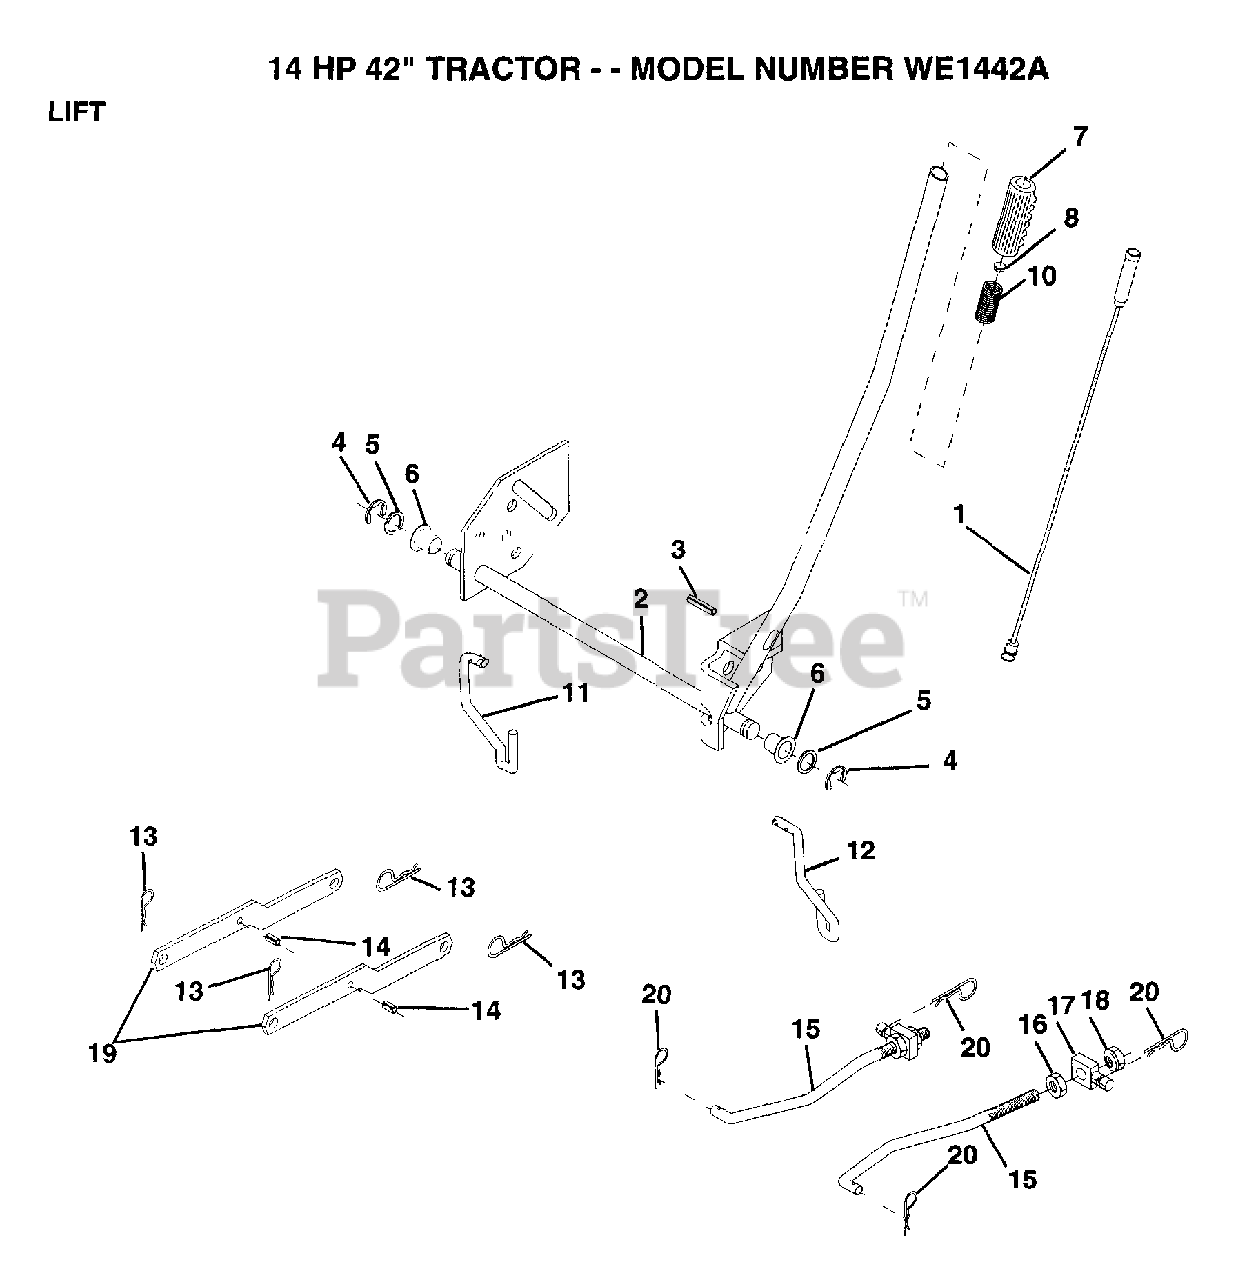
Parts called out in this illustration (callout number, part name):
1	WIRE ASM
3	PIN-GROOVE LT
5	WASHER
6	NYLON BEARING
7	GRIP
11	LINK LIFT LH
12	LIFT LINK RH
14	"PIN,SPRING"
15	LINK.FRONT
16	NUT
17	TRUNION
18	NUT.LK.W/WSH.1/2.
20	RETAINER.SPRING
